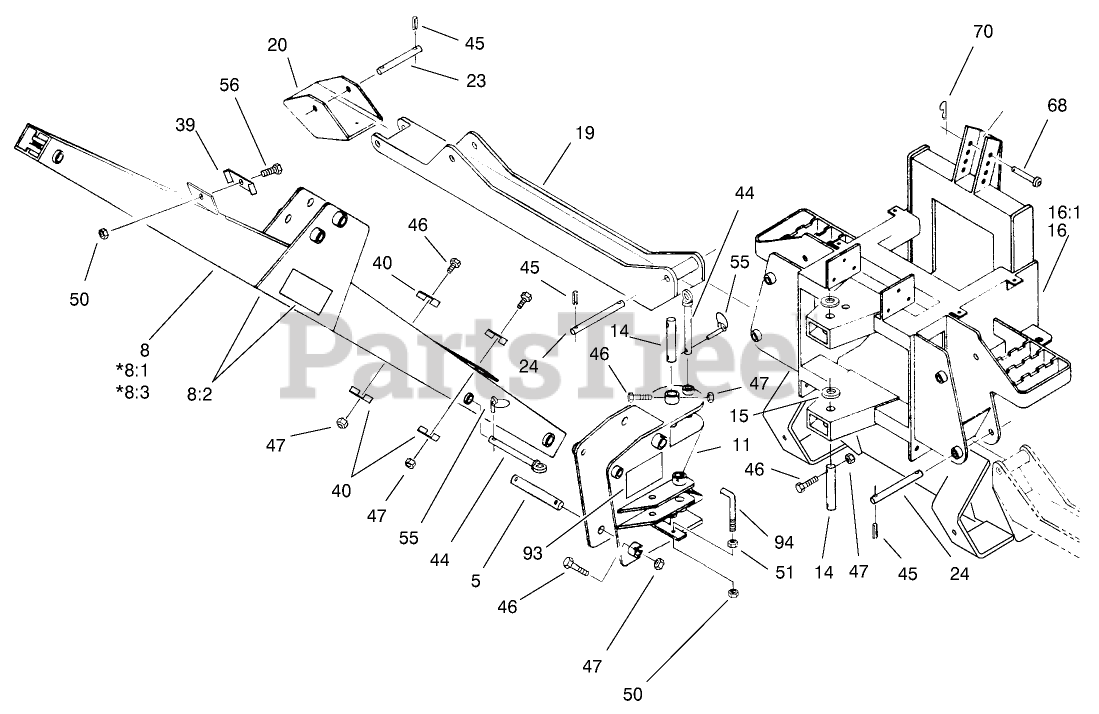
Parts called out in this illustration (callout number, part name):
5	PIN-BUCKET
8	BOOM ASM
8:2	DECAL-WARNING
11	SWIVEL ASM
14	PIN-PIVOT
15	WASHER-THRUST
16	BOX FRAME ASM
19	STABILIZER ASM
20	STABILIZER FOOT ASM
23	PIN-FOOT, STABILIZER
24	PIN-STABILIZER
39	BRACKET-HOSE
40	BRACKET-HOSE
44	LOCK PIN ASM
45	PIN-ROLL
46	SCREW-HH
47	NUT-LOCK
50	NUT-LOCK, NI
51	NUT-HEX
55	PIN-LYNCH
56	SCREW-HH
68	PIN-CLEVIS
70	PIN-HAIR
93	DECAL-PLACEMENT, PIN
94	BRACKET-HOSE
